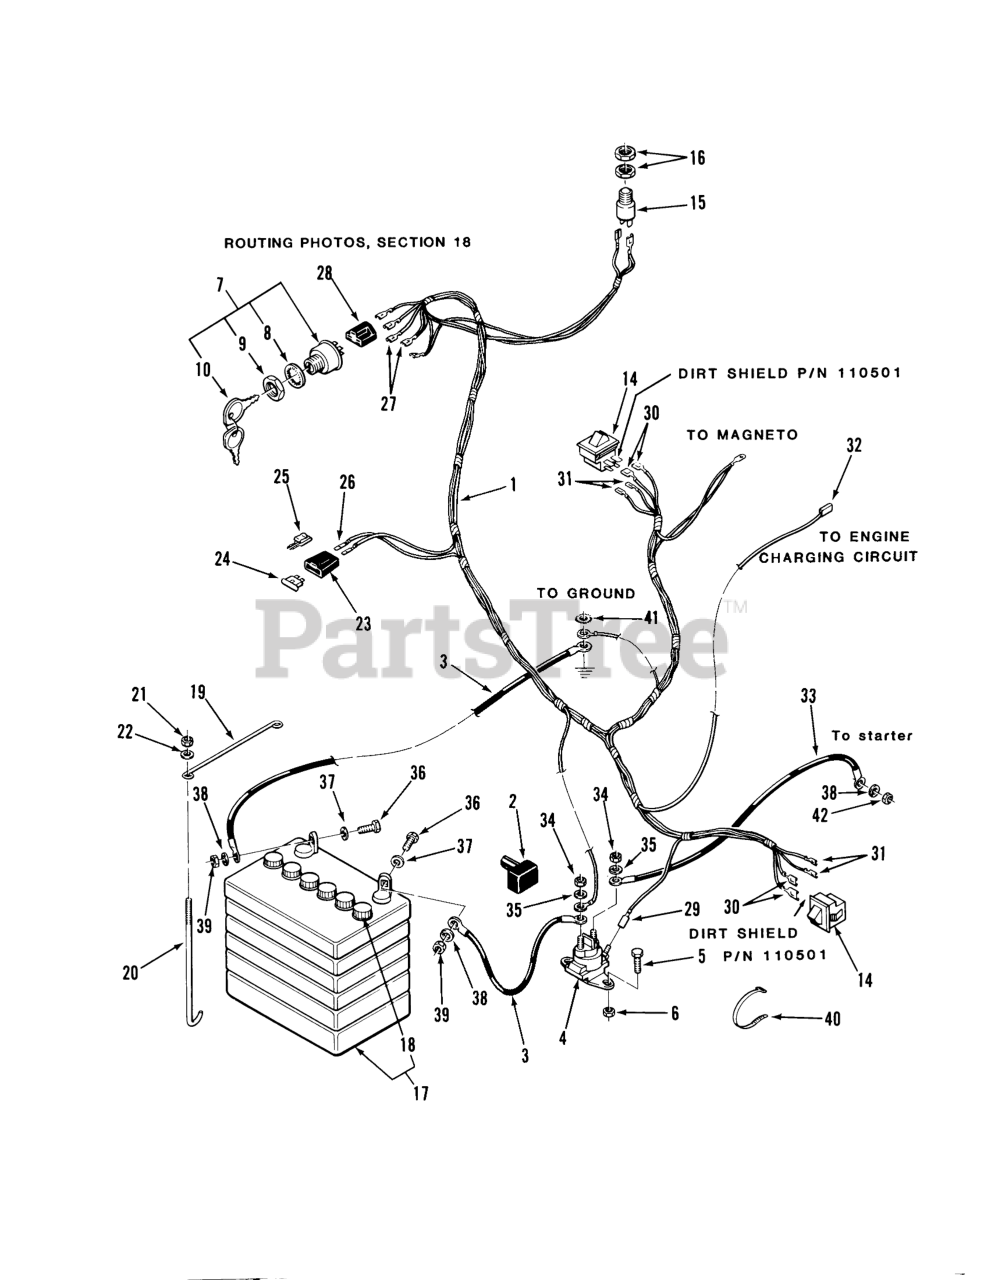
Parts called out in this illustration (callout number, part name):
1	HARNESS WIRING
2	Boot
3	Wire
4	Solenoid
5	Bolt
6	Nut
7	ASSY-SWITCH IGNITION
8	LOCKWASHER
10	Key-EL
14	PTO Interlock Switch
15	SWITCH-SEAT
16	NUT-HEX
17	Battery
19	Lockwasher
20	HOOK-BATTERY RETAINR
21	Nut
23	AUTO-FUSEBLOCK TERM
24	FUSE-BLADE, 15 AMP
26	TERMINAL-FUSE
27	Terminal
28	CONNECTOR-5 WAY-SERV
29	Terminal Part of 5
30	Terminal
31	Wire Terminal (Part of 1)
32	Terminal
33	Wire
34	Nut
35	Washer
36	Bolt
38	Washer
39	Nut
40	PLASTIC TIE
41	LOCKWASHER
42	Nut
